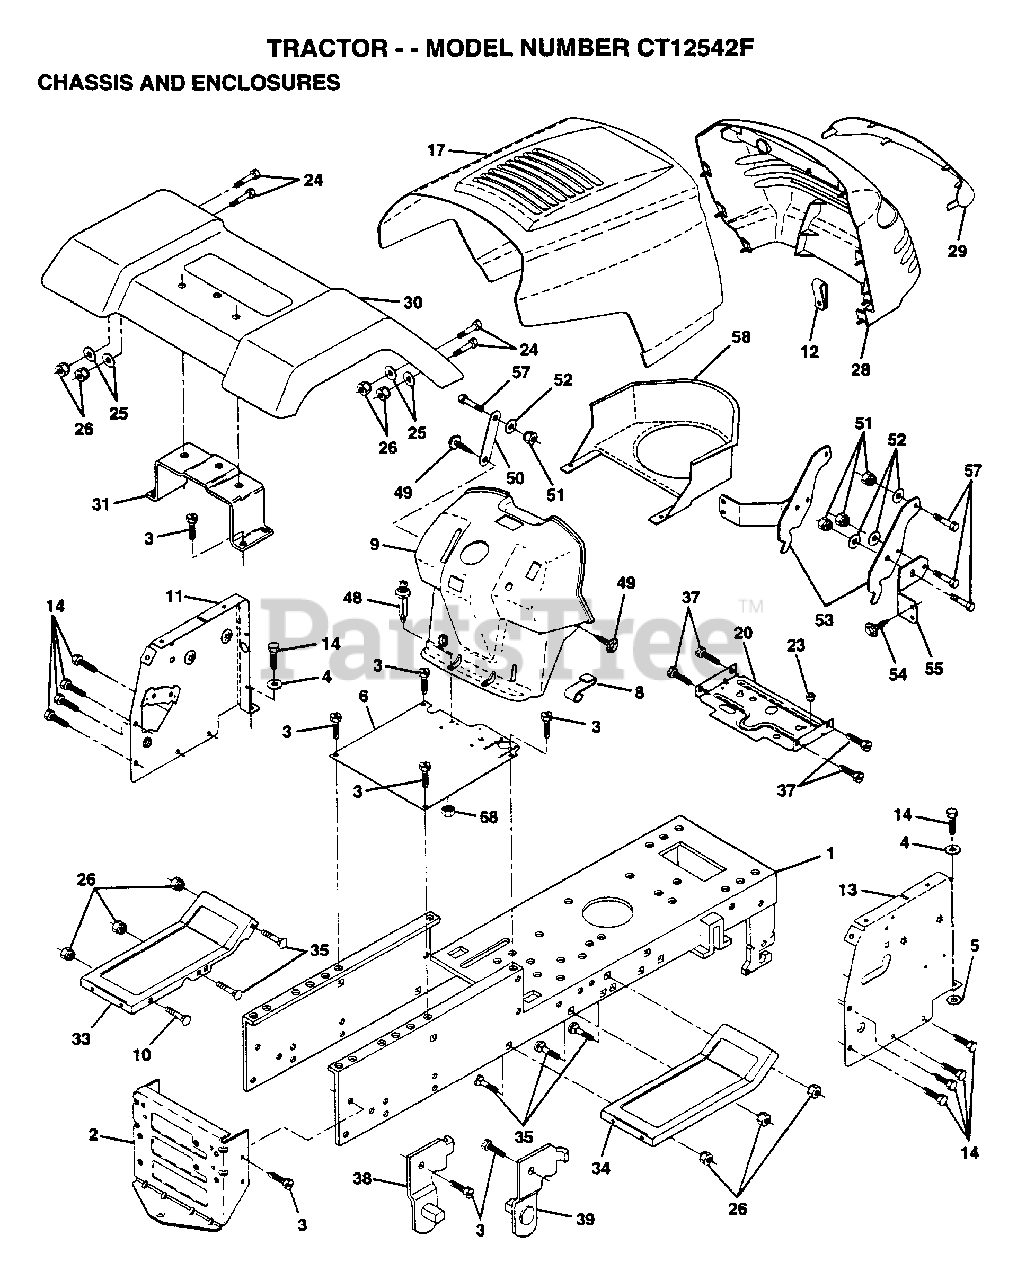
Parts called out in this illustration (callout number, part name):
3	SCREW
4	WASHER
5	LOCKWASHER
8	"CLIP,INSULATOR"
12	CLIP.TINNERMAN
14	SCREW LT
24	BOLT
25	WASHER
26	NUT
29	LENS GRILLE
31	BRKT FENDER
33	FOOTREST.LH.PERF.
34	FOOTREST.RH.PERF.
35	BOLT
37	SCREW
38	BRACKET ASM LH
39	BRACKET ASM RH
48	RIVET.PUSH.PLATE
49	SCREW HEX CRT
50	BRACE SUPT DASH
51	NUT
52	WASHER
53	HING PICK-OFF HD
55	BRACKET GRILLE
58	DUCT AIR 12-15H
68	NUT
